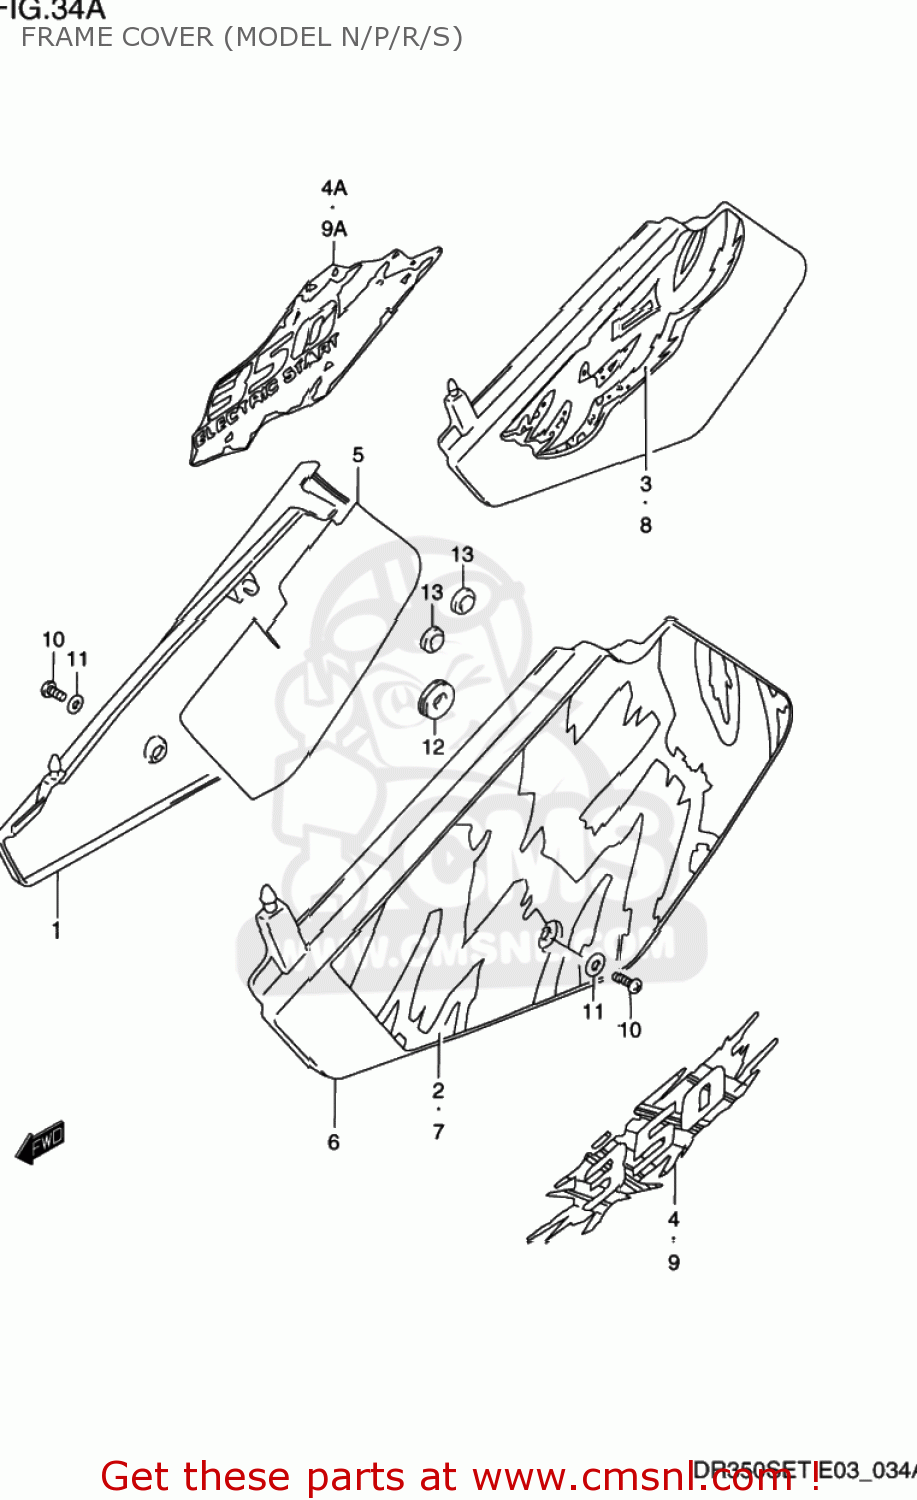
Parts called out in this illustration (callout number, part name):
1	COVER,FRAME,R(WHITE)
2	TAPE,FRAME COVER,RIGHT
3	EMBLEM,FRAME COVER,RIGHT
4	EMBLEM,FRAME COVER
4A	TAPE,FRAME COVER,R
5	SHIELD,FRAME COVER,R
6	COVER,FRAME,L(WHITE)
7	TAPE,FRAME COVER,LEFT
8	EMBLEM,FRAME COVER,LEFT
9	EMBLEM,FRAME COVER
9A	TAPE,FRAME COVER,LEFT
10	SCREW
11	WASHER
12	CUSHION
13	CUSHION
